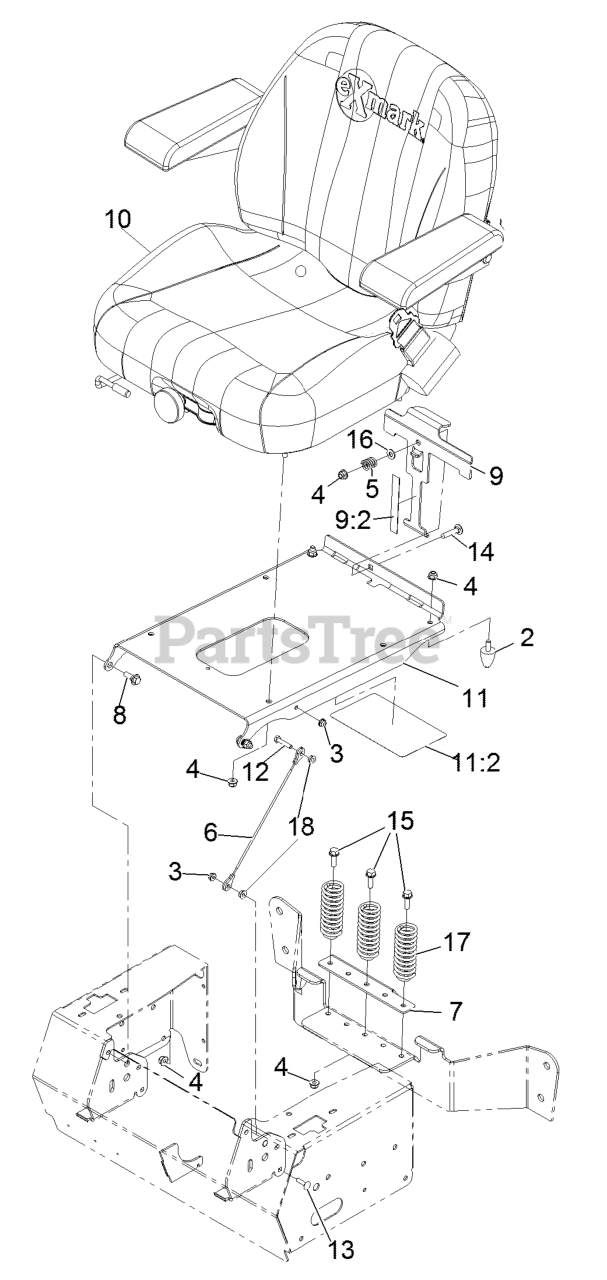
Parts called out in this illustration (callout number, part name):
2	BUMPER-SEAT
4	NUT-HF, NI
5	SPRING-COMPRESSION
6	CABLE-STOP, SEAT
7	CATCH,SEAT LATCH
8	SCREW-SHOULDER
9	ASM-SEAT LATCH
9:2	STRIP-POLY WEAR
11	PLATE, SEAT W/DECALS
11:2	DECAL-SERVICE AID
12	SCREW-HH
13	SCREW-CARR
14	BOLT-CARR
15	SCREW-HHF
16	WASHER-PLAIN
17	SPRING-COMPRESSION
